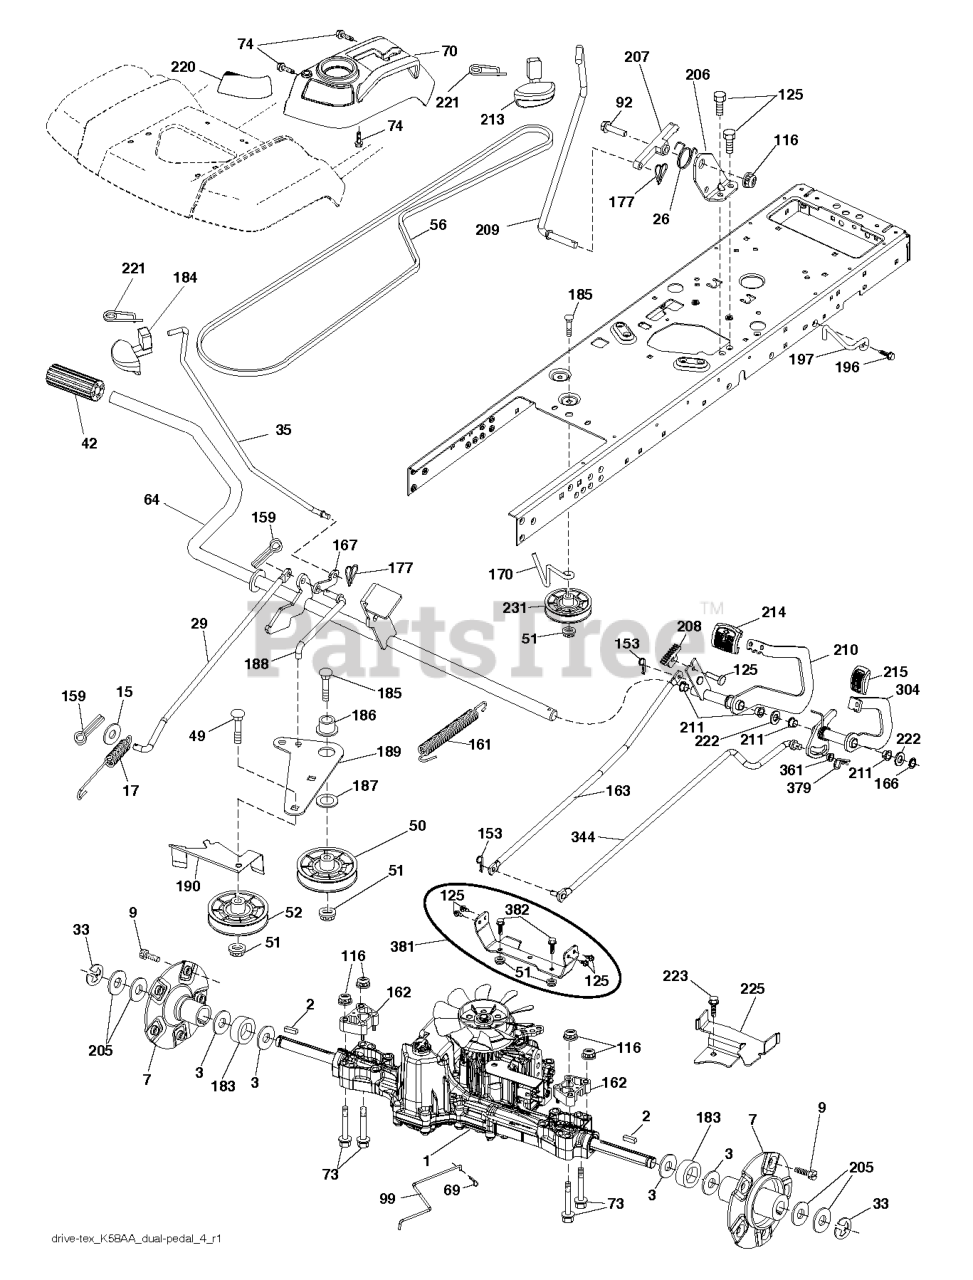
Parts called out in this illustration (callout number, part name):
2	KEY, 1/4 SQ X 1 1/4
7	HUB.PNT.GT.PM.1IN.AXLE.E-DIP
15	WASHER PLAIN WASHER 3/8 X 0.08
17	SPRING.BRAKE.K46.GREEN
26	SPRING.RETURN.CRUISE
29	ROD.BRAKE.K46
33	E RING HYT
42	PEDAL COVER
50	IDLER.FLAT.910.OFFSET
51	NUT LOCK FLG 3/8-16 UNC
52	IDLER.V-GROOVE.910.OFFSET
64	SHAFT.ASM.PEDAL.BRK.CNTR
69	HAIRPIN.SOFT.ZINC.059X1.125
70	CONSOLE.ASM.RH.GT.FC.HUSQ
73	BOLT.HEX.FLNG.5/16-18X3.75
125	SCREW
153	RETAINER M
161	SPRING, RETURN LT
166	NUT.PUSH.625
167	LATCH.BRAKE.SPRING
170	KEEPER.CENTER SPAN.1.688
177	PIN COTTER;LOCKING;BOWTIE;1IN
183	SPACER.SPLIT;1.00.ID 1.75"
184	HANDLE.PARKING.BRAKE.H (BLK)
186	SPACER.RETAINER
188	LINK.CLUTCH.GROUND DRIVE.LONG
189	BELLCRANK.GROUND.DRIVE.TEX.
190	KEEPER.BELLCRANK.DRIVE
196	SCREW 3/8-16X1
206	BRACKET.MOUNT.CRUISE.LATCH
211	BEARING.NYLON
213	KNOB.CONTROL.CRUSIE.HU
214	PEDAL.FORWARD.PAD.TEX
220	REFLECTOR.RH.TEX GT
221	RETAINER.SPRING.CLIP.H
222	WASHER 21/32 X 1-1/4 X 10 GA.
225	KEEPER.BELT.TRANSAXLE.K46
231	IDLER.V-GROOVE.1.688.OFFSET
381	Service Kit
